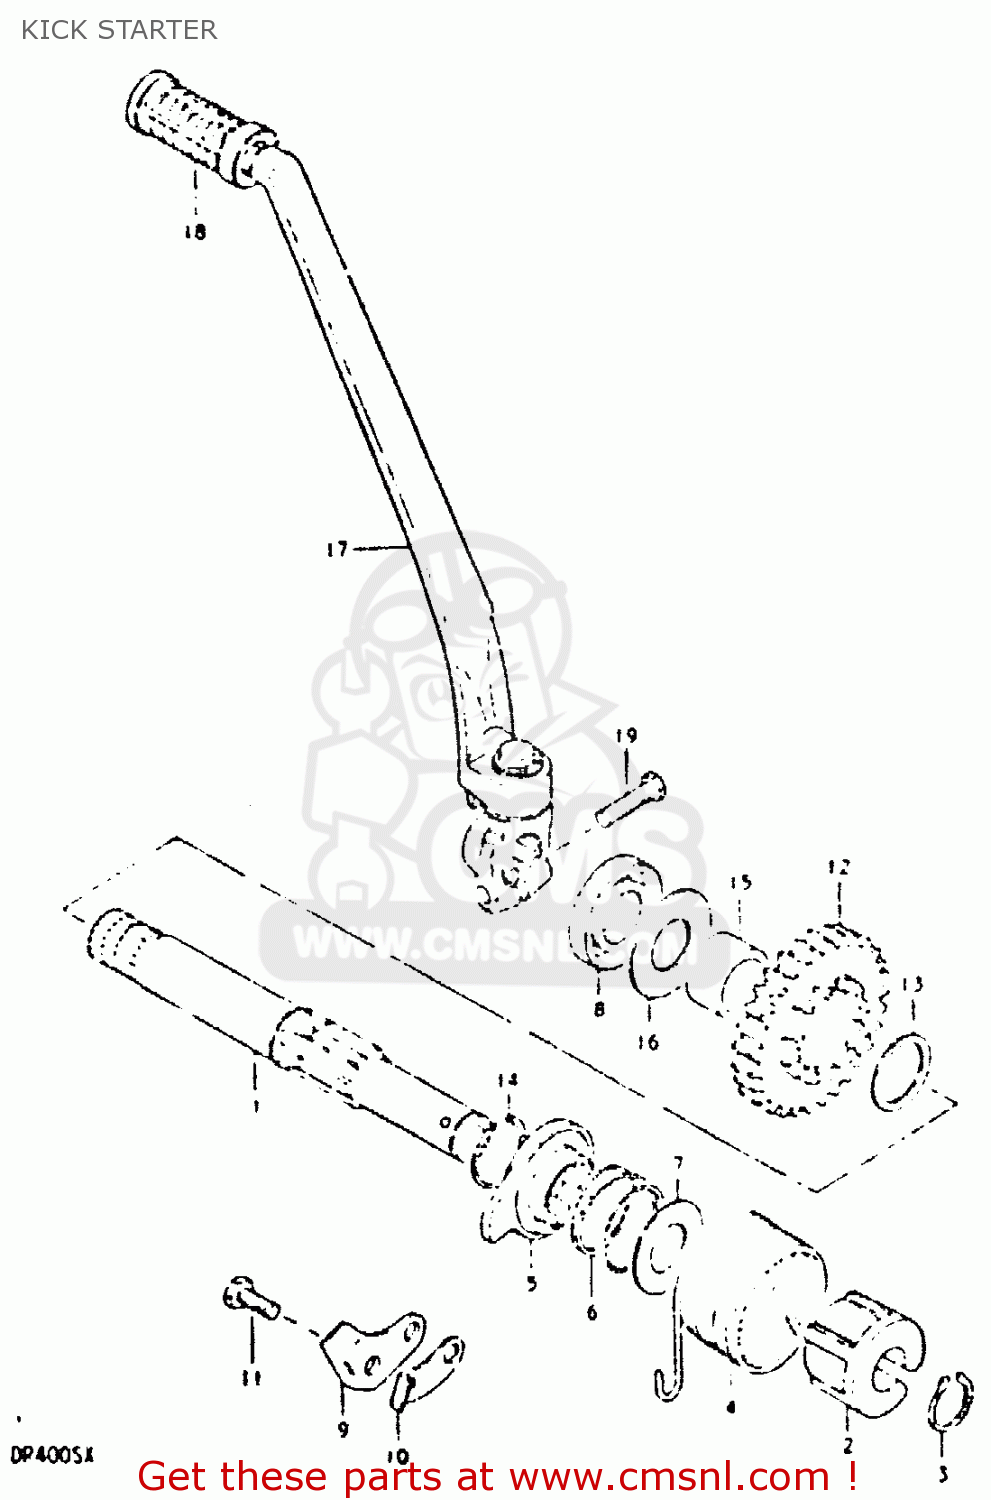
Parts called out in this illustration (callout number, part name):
1	SHAFT,KICK STARTER
2	GUIDE,KICK STARTER SFT SPRING
3	CIRCLIP
4	SPRING
5	STARTER,KICK
6	SPRING
7	PLATE
8	SEAL,OIL(20X37X7)
9	GUIDE,KICK STARTER
10	STOPPER,KICK STARTER
11	BOLT
12	GEAR,KICK STARTER DRIVE(NT:29)
13	WASHER,LOCK
14	CIRCLIP
15	SPACER
16	PLATE, OIL RESERVOR
17	LEVER ASSY,KICK STARTER
18	RUBBER,KICK STARTER PEDAL
19	BOLT(8X25)
